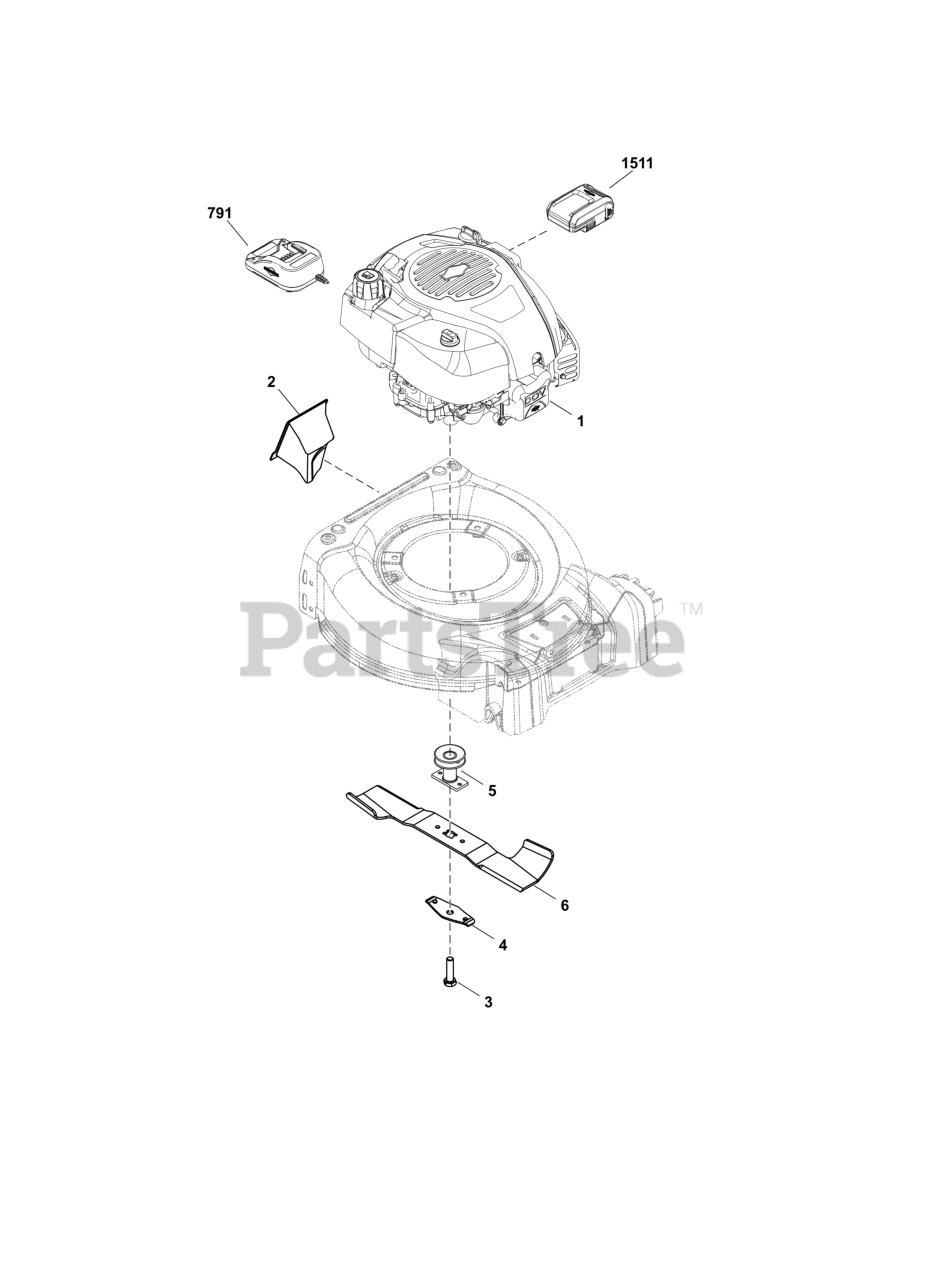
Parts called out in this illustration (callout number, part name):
1	*ENGINE, Briggs & Stratton
2	MULCH PLUG
3	SCREW Hex, 3/8-24 x 1-1/2
4	SUPPORT, Blade Bell
5	BLADE ADAPTER
791	CHARGER, Battery
1511	BATTERY
